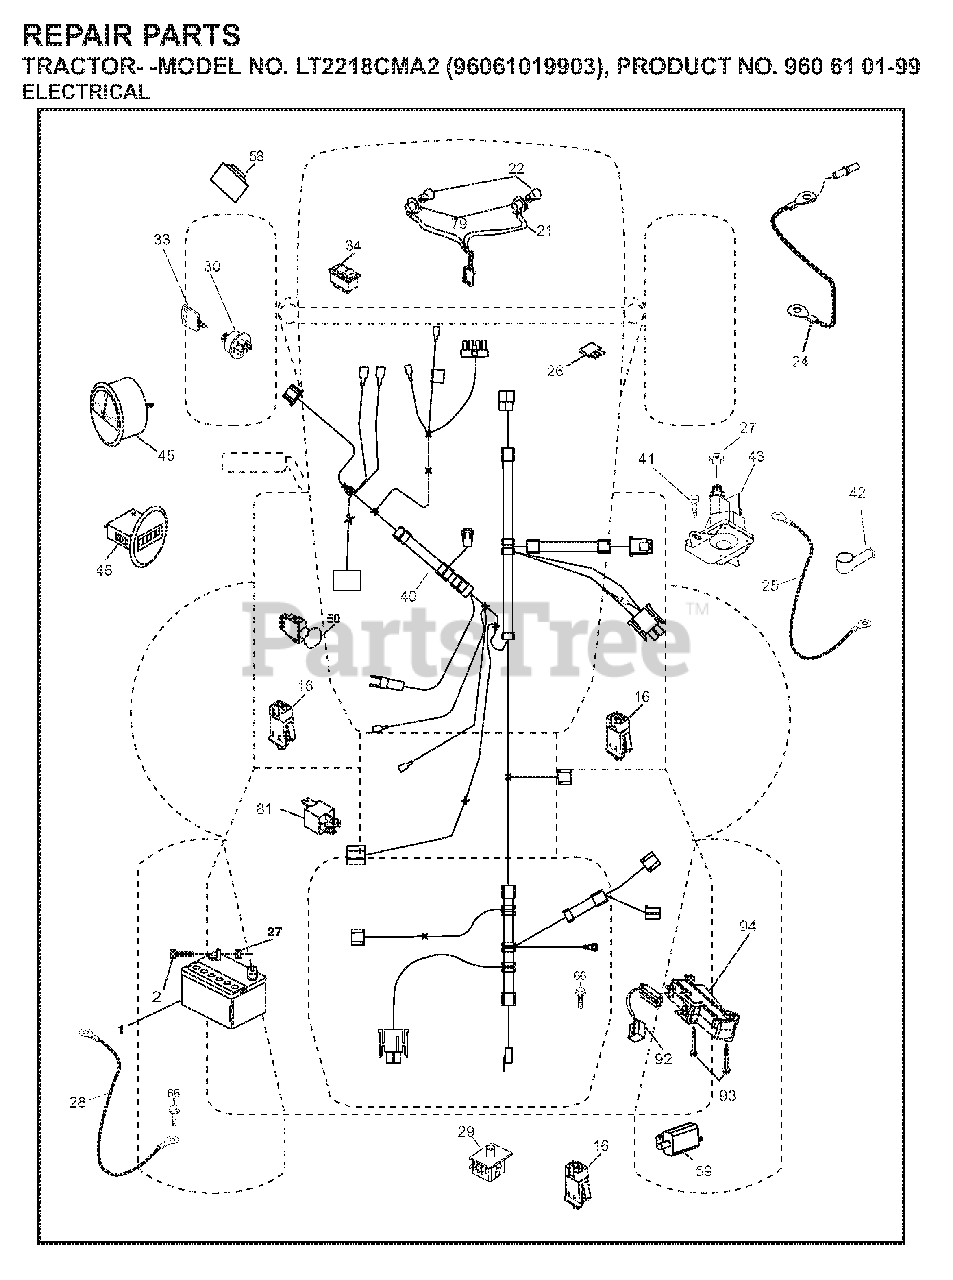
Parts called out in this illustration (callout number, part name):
1	REPL BY 532 12 38-99
16	SWITCH INTERLOOK PUSH-IN
21	HARNESS.W/LIGHT SOCKET
22	LIGHTBULB
24	BATTERY CABLE GT
25	CABLE BATTERY
26	FUSE 20AMP
27	NUT
28	CABLE GROUND
29	SWITCH.SEAT.DP W/RAMPS
30	SWITCH.IGN.DELTA.W.LGH.ROS
33	KEY.CHAIN.BLISTER.PACK.GEN.INT
34	SWITCH LT
42	TERMINAL COVER
43	SOLENOID.W/BRASS.PLUNG
46	HOURMETER SNAP-IN
50	PTO SWITCH
58	BUZZER
79	BULB HOLDER ASM.
81	RELAY.ASSY.T
92	HARNESS.PIGTAIL.CONSLE
93	SCREW.PLASTITE
94	MODULE.REVERSE.ROS
